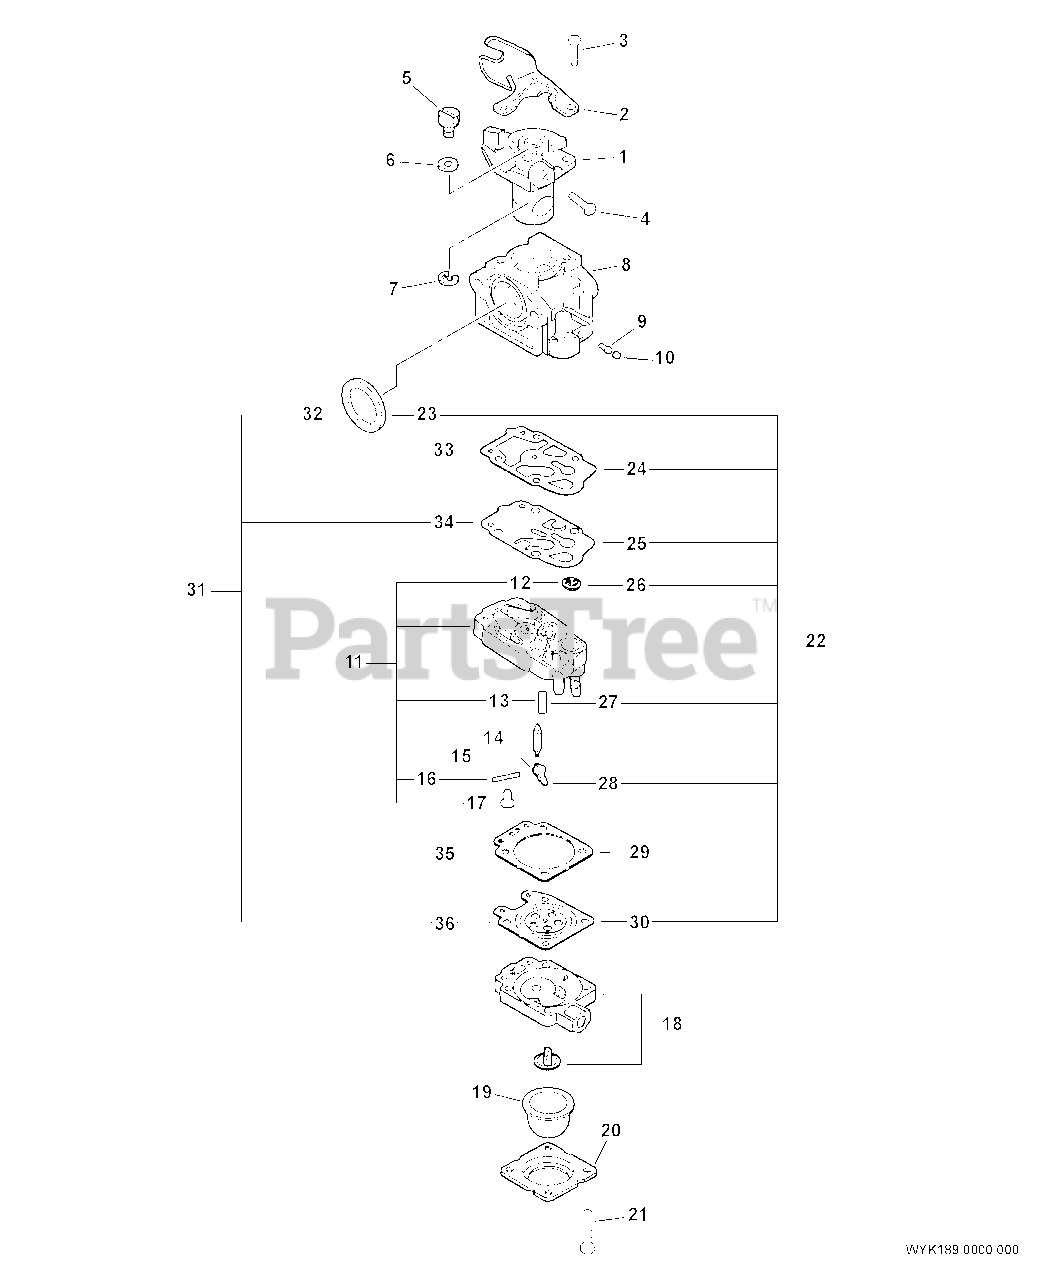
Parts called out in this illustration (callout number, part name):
1	THROTTLE VALVE ASSY
2	BRACKET, THROTTLE CABLE
8	BODY, CARBURETOR
9	NEEDLE, HIGH SPEED
11	BODY ASSY, PUMP
12	STRAINER
13	SPRING, METERING LEVER
14	VALVE, INLET NEEDLE
15	LEVER, METERING
16	PIN, METERING LEVER
18	BODY ASSY, PURGE
19	BULB, PURGE
20	RETAINER, PURGE BULB
22	REPAIR KIT
23	SEAL
24	GASKET, PUMP
25	DIAPHRAGM, PUMP
26	STRAINER
27	VALVE, INLET NEEDLE
28	LEVER, METERING
29	GASKET, DIAPHRAGM
30	DIAPHRAGM, METERING
31	GASKET / DIAPHRAGM KIT
32	SEAL
33	GASKET, PUMP
34	DIAPHRAGM, PUMP
35	GASKET, DIAPHRAGM
36	DIAPHRAGM, METERING
